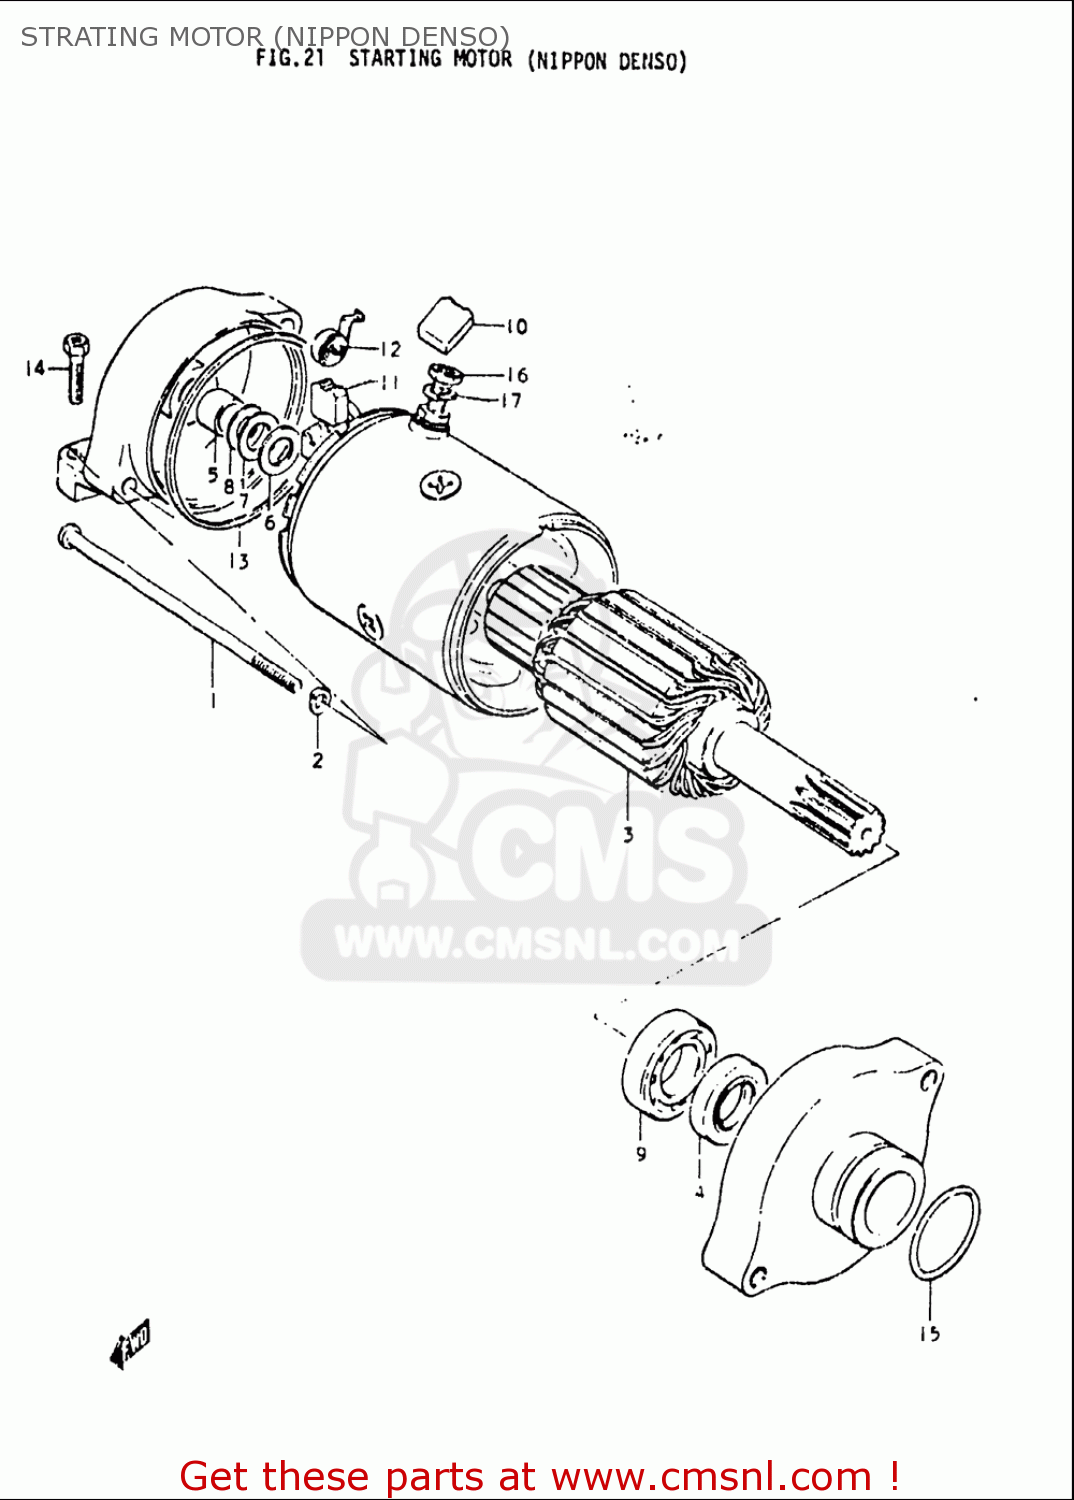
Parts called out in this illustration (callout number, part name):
2	WASHER,LOCK
4	SEAL,OIL
6	SHIM, (1)
7	SHIM, (2)
8	SHIM, (3)
9	BEARING
10	BRUSH(-)
12	SPRING
13	GASKET
14	SCREW (6X25)
15	O RING(D:2,ID:24.5)
16	NUT
17	WASHER,LOCK
